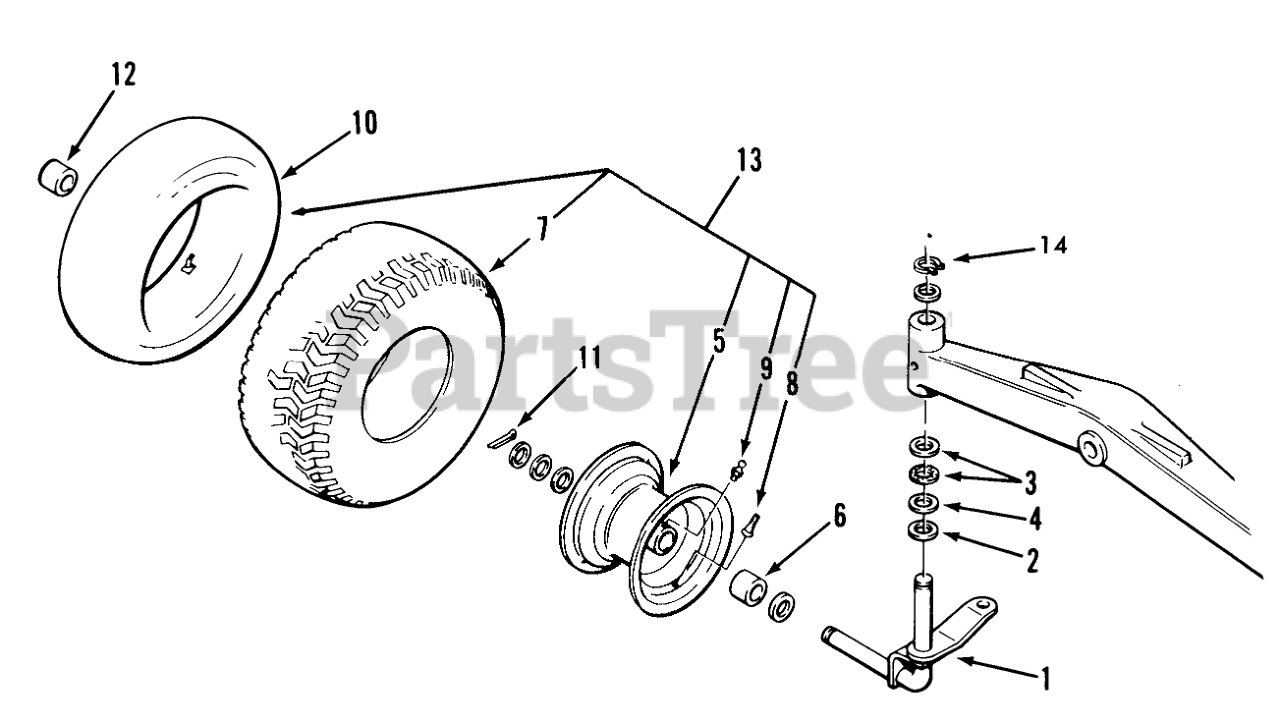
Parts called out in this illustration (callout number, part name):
1	RH SPINDLE ASM
2	Race Thrust
3	WASHER-SLIP
4	WASHER
5	Wheel (includes Grease Fitting, Bearings & Valve)
6	BEARING-RADIAL FLNGE
7	TIRE TURF SAVER 16X6.50-8
8	VALVE
9	ZERK-GREASE
10	TUBE-INNER
11	COTTER PIN-4
12	CAP-HUB
13	Hood & Grill 211-4 & 211-5
14	Snap Ring
